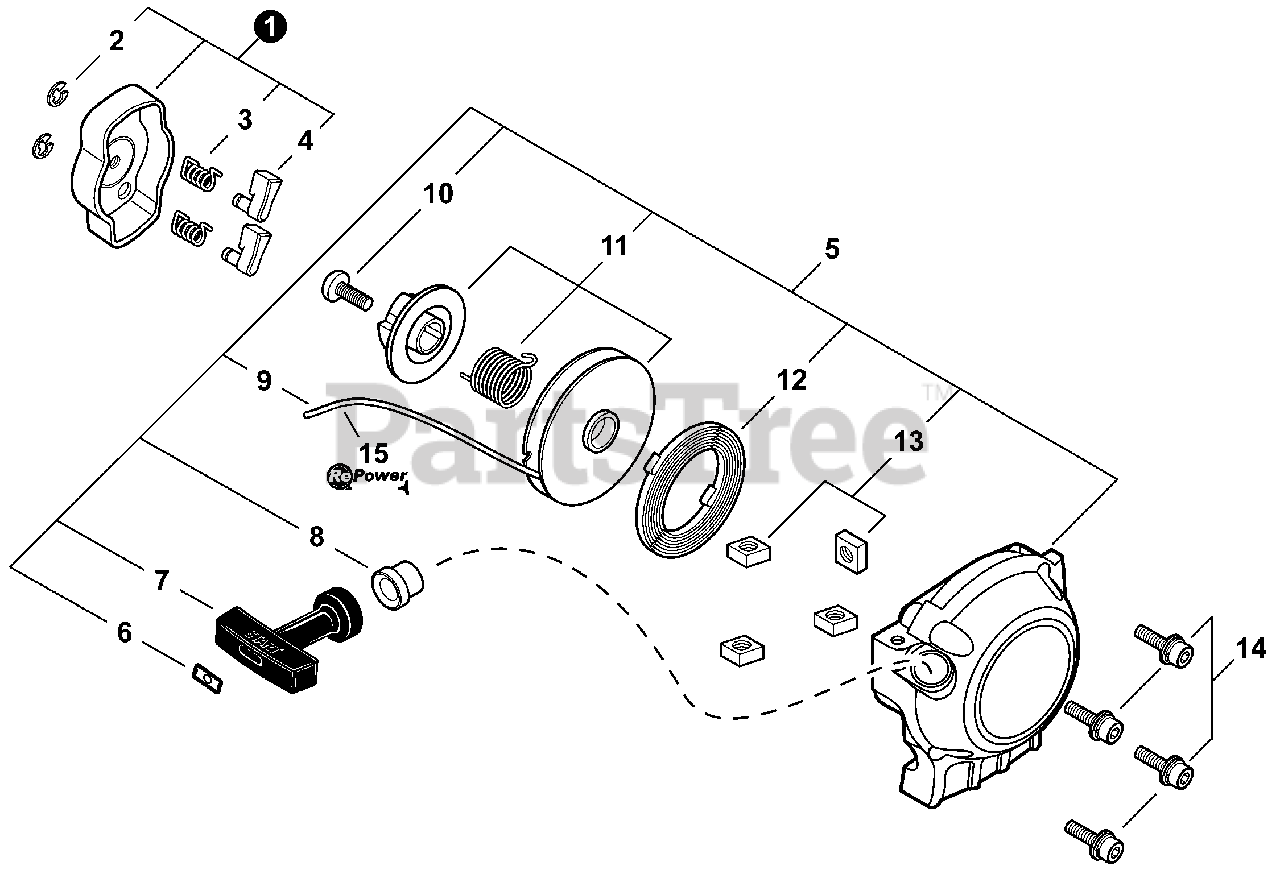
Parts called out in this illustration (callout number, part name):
1	PAWL ASSY, STARTER
2	E-RING 4
3	SPRING, RETURN
4	PAWL, STARTER
5	STARTER ASSY, RECOIL
6	RETAINER, ROPE
7	GRIP, STARTER
8	GUIDE, ROPE
9	ROPE, STARTER
10	SCREW 5
11	REEL/CAM PLATE SET
12	SPRING, RECOIL
13	NUT
14	BOLT 4x16
15	BULK STARTER ROPE - 3.0 MMx61 M
